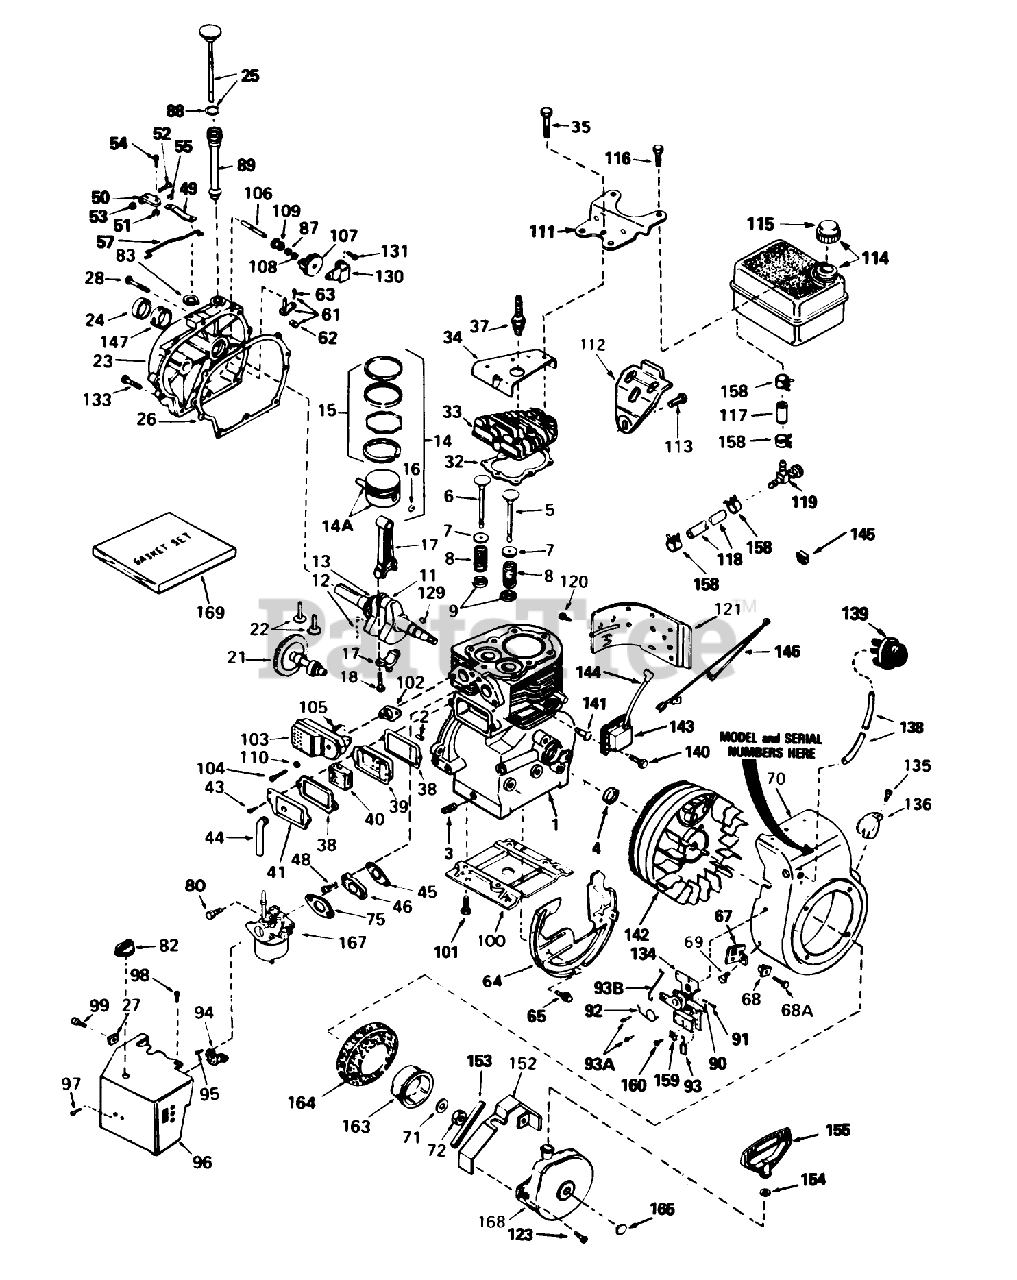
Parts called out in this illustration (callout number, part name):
1	Cylinder Assy. (Incl. Ref. #2, 3 4)
2	Pin-Dowel
3	Plug-Drain, Oil (SQH 1/4-18)
4	Oil Seal
5	Valve, Intake (Standard)(Incl. No. 9)
5	Valve, Intake (1/32" oversize)(Incl. No. 9)
6	Valve, Exhaust (Standard)(Incl. No. 9)
6	Valve, Exhaust (1/32" oversize)(Incl. No. 9)
7	Cap-Spring, Valve
8	Spring-Valve
9	Keeper-Spring, Valve
11	Crankshaft Assy. (Incl. Ref. #12 13)
12	Pin, Groove
13	Gear-Crankshaft
14	Piston, Pin Ring Assy. (Std.)(Incl. Ref. #14A, 15 16)
14	Piston, Pin Ring Assy. (.010 Oversize)(Incl. Ref. #14A, 15 16)
14	Piston, Pin Ring Assy. (.020 Oversize)(Incl. Ref. #14A,15 16)
14A	Piston Pin Assy. (Std.)(Incl. Ref. #16)
14A	Piston Pin Assy. (.010 Oversize)(Incl. Ref. #16)
14A	Piston Pin Assy. (.020 Oversize)(Incl. Ref. #16)
15	Ring Set (Std.)
15	Ring Set (.020" OS)
15	Ring Set (.010" OS)
17	Rod Assy., Connecting (Incl. Ref. #18)
18	Bolt, Connecting Rod
21	Camshaft, BCR
22	Lifter-Valve
23	Cover, Cylinder (Incl. Nos. 24 106)
24	Oil Seal
25	Dipstick, Oil (Incl. Ref. #88)
26	Gasket-Cover, Cylinder
27	Nut-U Type
28	Screw (1/4-20 x 1-1/4)
32	Gasket-Head, Cylinder
33	CYLINDER HEAD
34	Cover-Head, Cylinder
35	Screw (5/16-18 X 2-1/2)
37	Plug, Spark (J17LM or equiv.)
37	Plug, Spark (Champion RCJ-8)
38	Gasket-Breather
39	Body-Breather
40	Element-Breather
41	Cover-Valve
43	Screw
44	Tube-Breather
45	Gasket-Intake
46	481-1279 SENATOR RO
48	Screw
49	Lever-Governor
50	Clamp-Lever, Governor
51	Nut-Lock
52	Screw
53	Nut-Lock
54	Screw
55	Washer-Lock
57	Governor Link
61	Rod, Governor (Incl. Nos.62 63)
62	Yoke-Governor
63	Screw (6-40x5/16)
64	Baffle Blower Housing
65	Screw (1/4-20x19/32)
67	Bracket
68	Grommet
68A	Screw
69	Screw
70	Housing, Blower (Incl. Ref. #135 136)
71	Washer-Belleville
72	Flywheel Nut
75	Gasket-Carburetor
80	Screw-Hex Hd.
82	Knob-Control
83	Ring-Retaining
87	Washer-Flat
88	O-Ring
89	Tube Fill
90	Spring-Compression
91	Screw
92	Spring-Throttle
93	Terminal
93A	Screw (10-32 x 1/2)
93B	Link-Throttle
94	Bracket-Choke
95	Screw (10-32 x 1/2)
96	Carburetor Cover
97	Screw (8-32 X 5/16)
98	Screw (10-32x1/2)
99	Screw (8-32 x 3/8)
100	Base Engine
101	Screw
102	Gasket Exhaust
103	Muffler
104	Screw (5/16-18 X 2)
105	Screw
106	Shaft-Governor
107	Governor Gear ASM
108	Ring-Retaining
109	Spool-Governor
110	Washer
111	Plate, Fuel Tank Mounting
112	Bracket, Fuel Tank Mounting
113	Screw (1/4-20x19/32)
114	481-1261 SENATOR TI
115	Cap, Fuel
116	Screw (1/4-15x7/8)
117	Line-Fuel
118	Line-Fuel (8.62)
119	Valve-Shut Off
120	Screw
121	Extension-Blower Hsng.
123	Screw
129	Key-Flywheel
130	Bracket, Governor
131	Screw (10-24x1/2)
133	Screw
134	Control Assy., Remote Speed (Incl. Ref. #90 thru 93)
135	Screw (8-32 x 3/8)
136	Screw
138	Line-Primer
139	Primer Assy.
140	Screw
142	Flywheel
143	Solid State
144	Cover-Spark Plug
145	Clip-Wire
146	Ground Wire
147	Bushing-Crankshaft
152	Guard-Starter
153	Seal, Snowguard
154	Washer
155	Handle-Starter, Mitten Grip
158	Clamp-Line, Fuel
159	Conduit
160	Screw (10-32 x 3/8)
163	Cup-Starter
164	Screen-Starter
165	Plug-Starter
167	Carburetor (Incl. Ref. #75)
168	Starter-Rewind
169	Gasket Set (Incl. Items Marked *)
